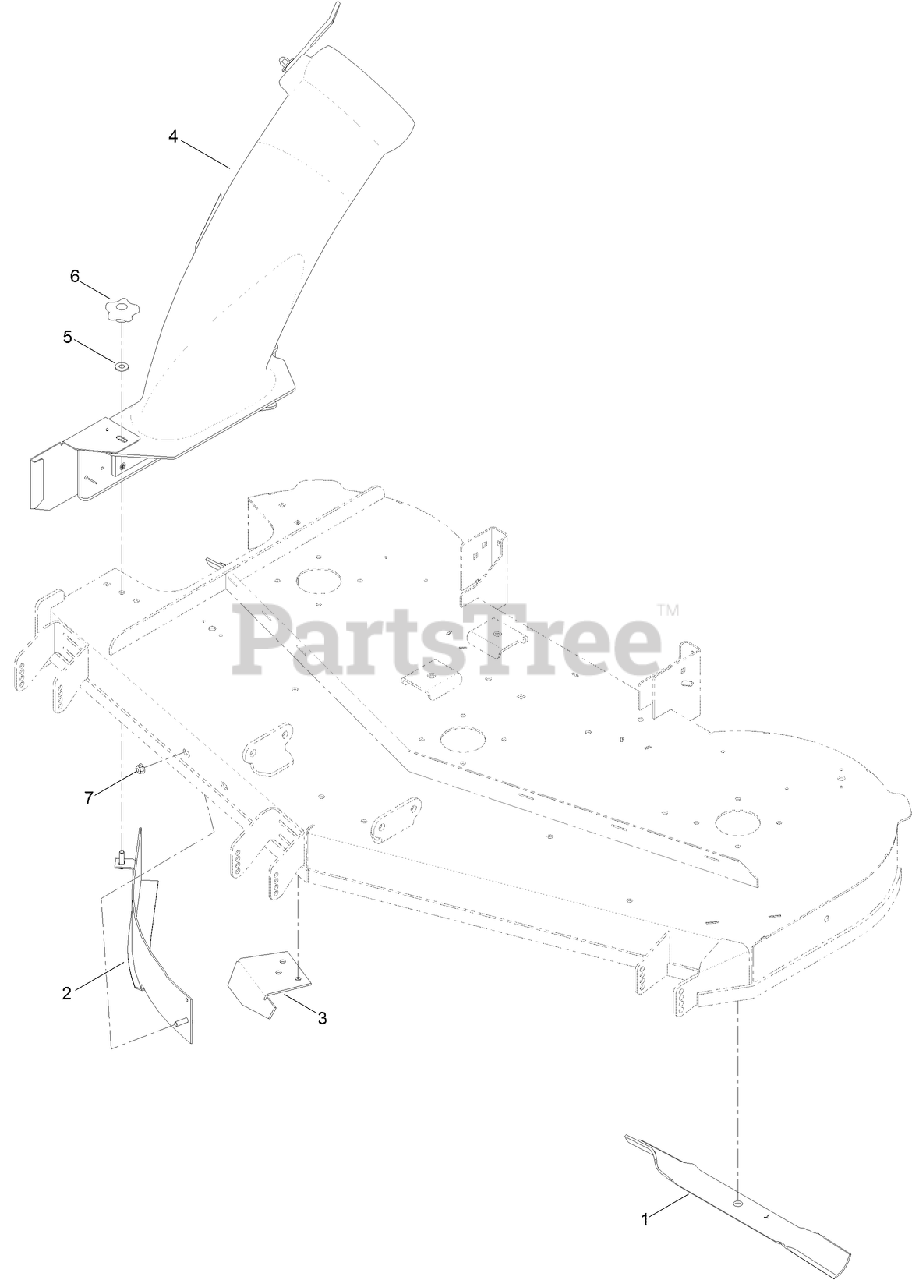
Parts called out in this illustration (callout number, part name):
1	BLADE-20.50 INCH
2	BAFFLE ASM
3	BAFFLE-CUTOFF
4	BAGGER BOOT ASM
5	WASHER-FLAT
6	KNOB-HANDLE
7	NUT-HF, NI
